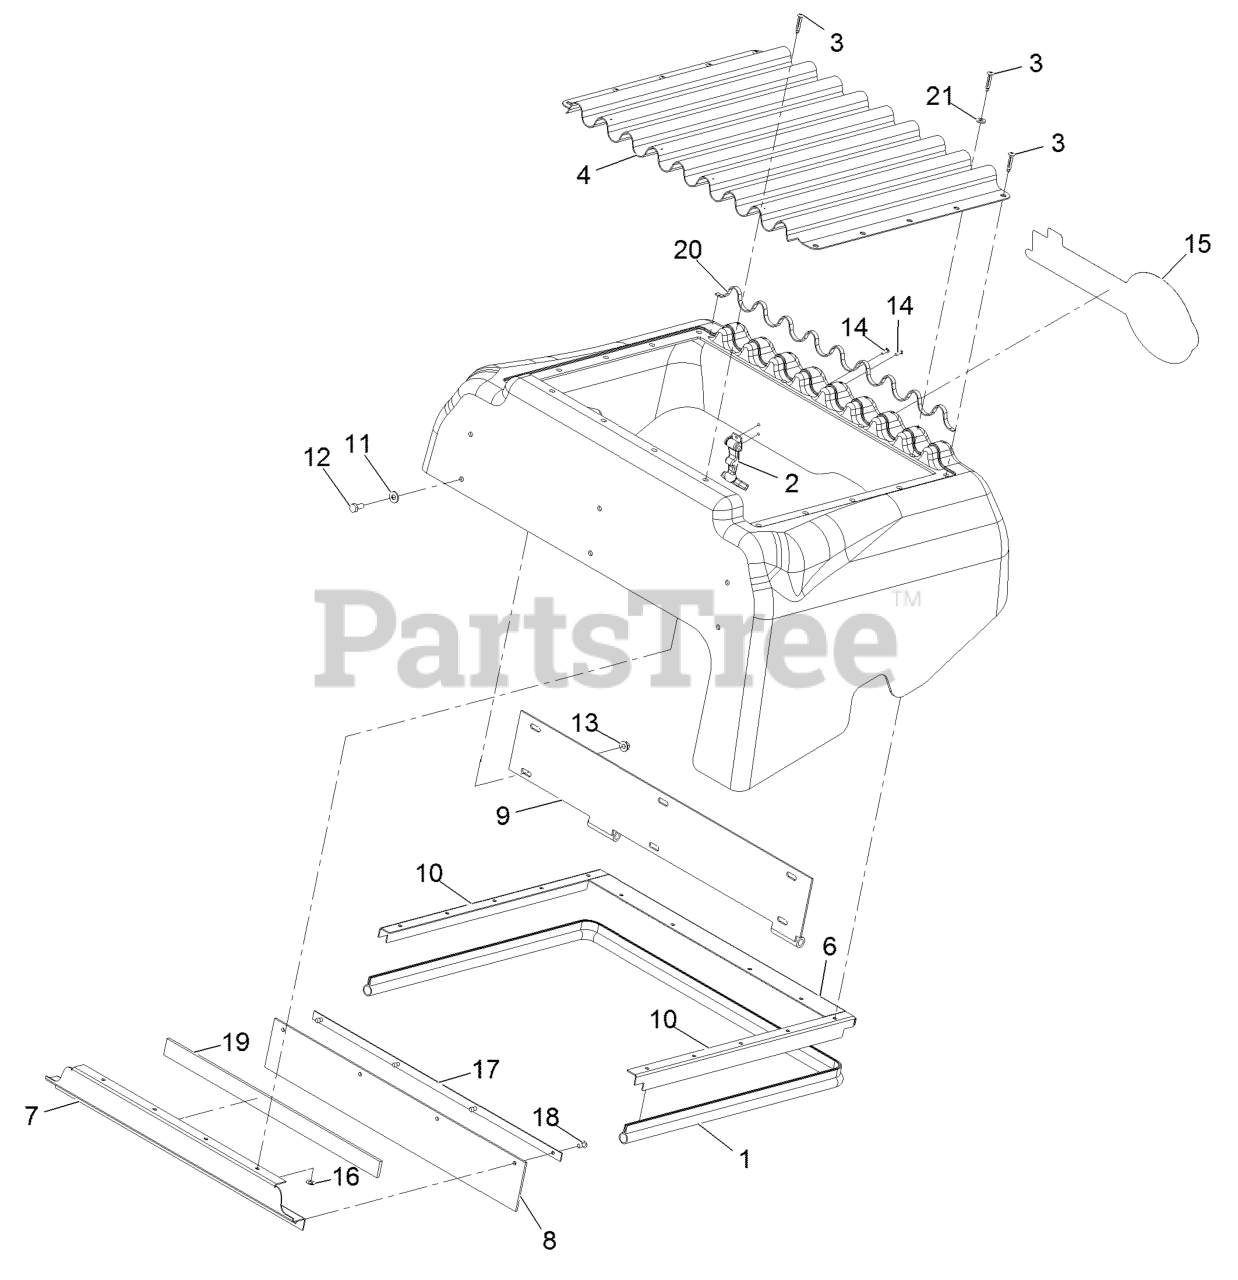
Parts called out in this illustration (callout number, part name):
1	Seal-Trim 54.6
2	LATCH-RUBBER
4	SCREEN, RADIATOR
6	MOUNT-SEAL REAR
7	MOUNT-SEAL FRONT
8	SEAL-RADIATOR HOOD
9	WLD, HINGE
10	MOUNT-SEAL SIDE
11	WASHER-FLAT
12	SCREW-HH
15	DECAL,EXMARK
16	WASHER-SPRING
17	PLATE-SEAL BACKUP
18	Rivet-Pop
19	SEAL-FRONT SCREEN
20	SEAL-REAR SCREEN
21	WASHER-FLAT
